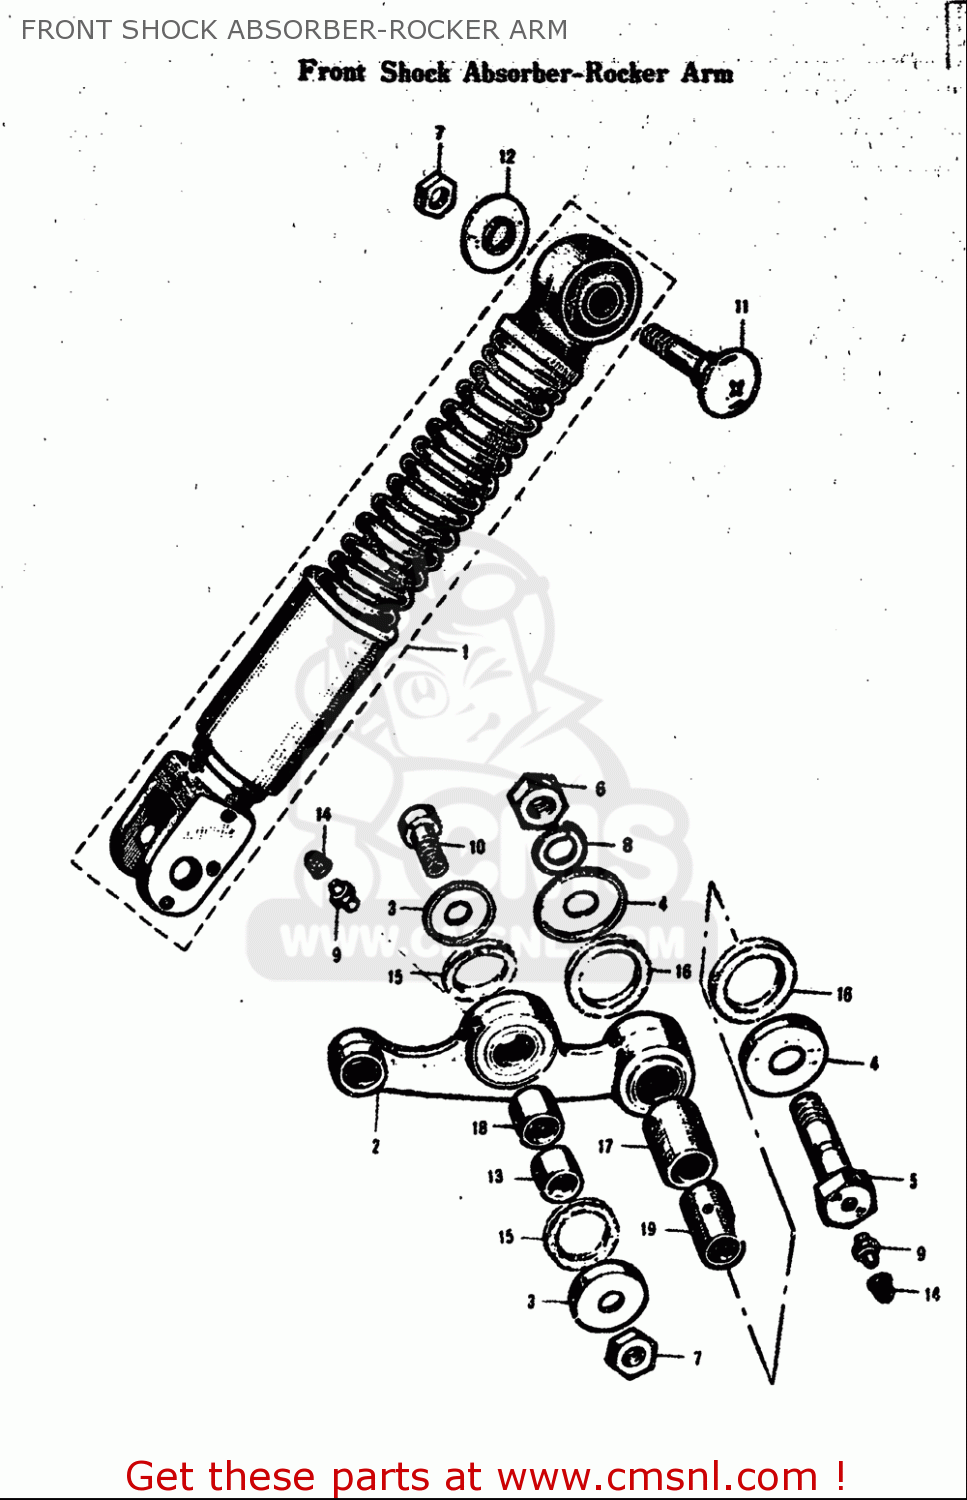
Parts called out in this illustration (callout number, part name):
6	NUT
7	NUT
8	WASHER,LOCK
9	NIPPLE
